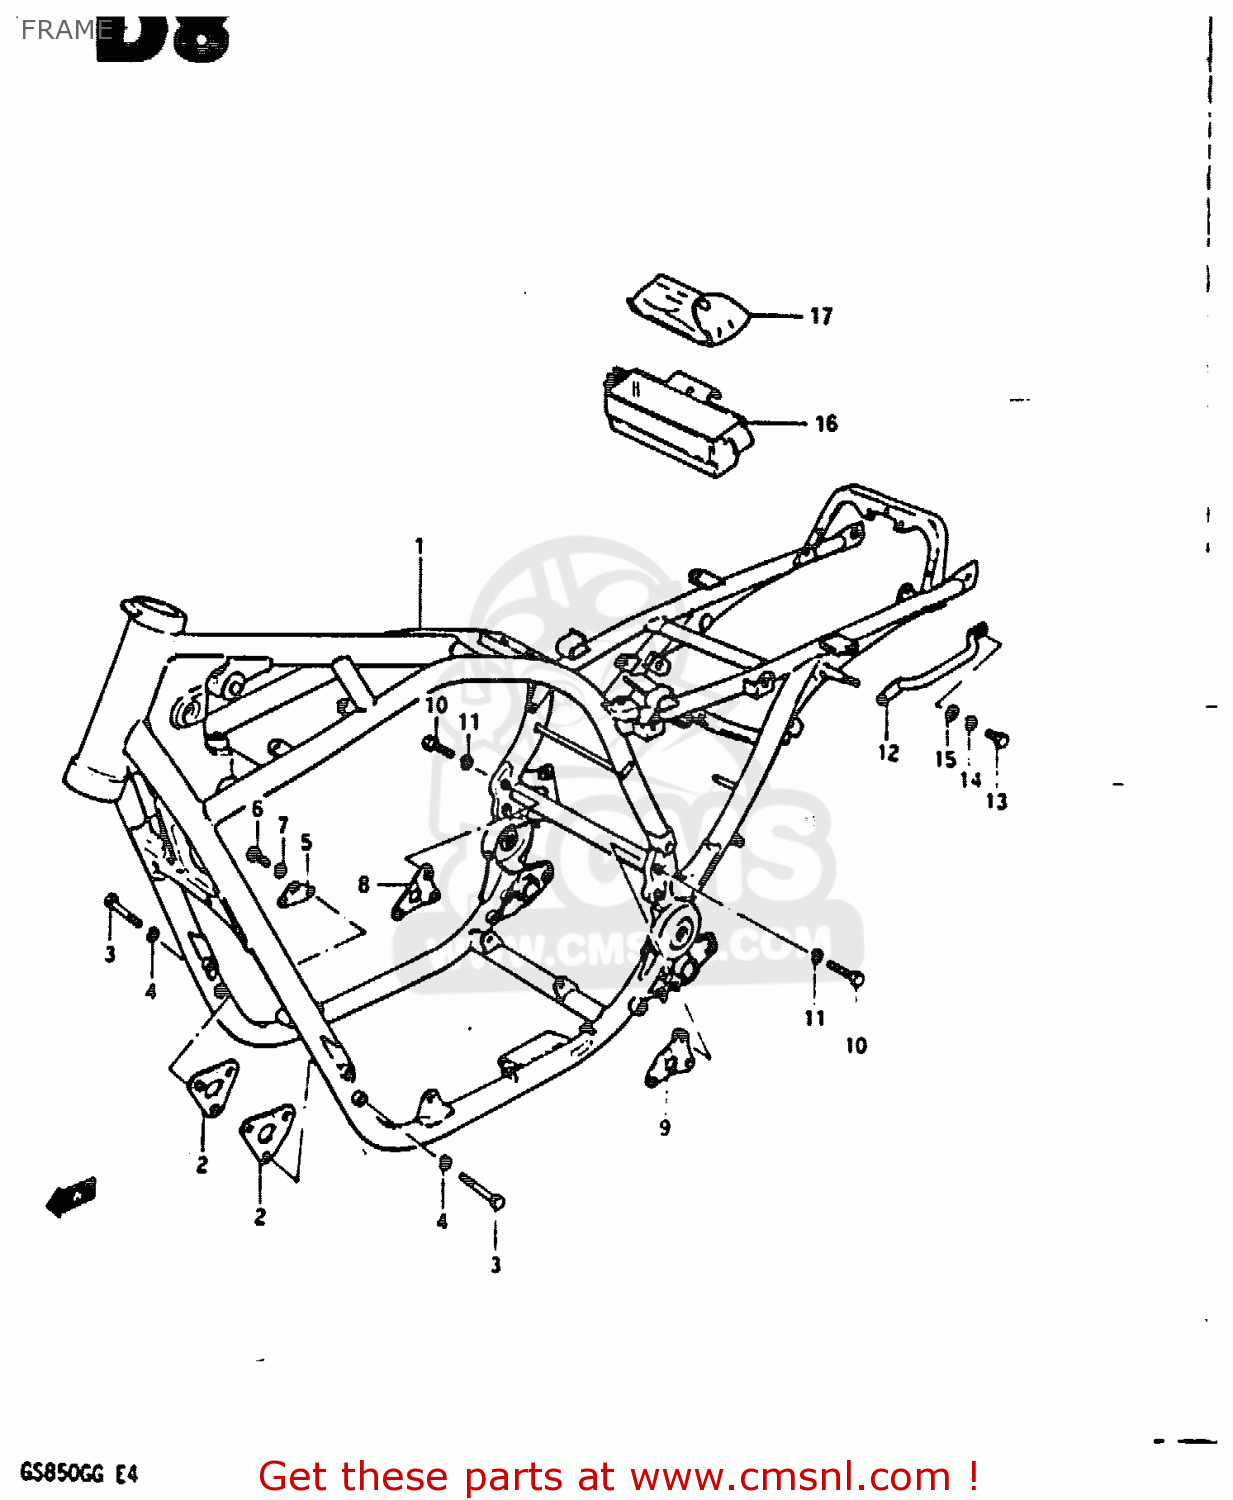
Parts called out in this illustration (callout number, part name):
1	FRAME
2	PLATE,ENGINE MOUNTING
3	BOLT
4	WASHER,LOCK,8.
5	PLATE,ENGINE MOUNTING
6	BOLT
7	WASHER,LOCK,8.
8	PLATE,ENGINE MOUNTING
9	PLATE,ENGINE MOUNTING
10	BOLT 8X40
11	WASHER,LOCK,8.
12	GRIP,FRAME HANDLE
13	BOLT
14	LOCK WASHER
15	WASHER
16	HOLDER,TOOL
17	TOOL SET
